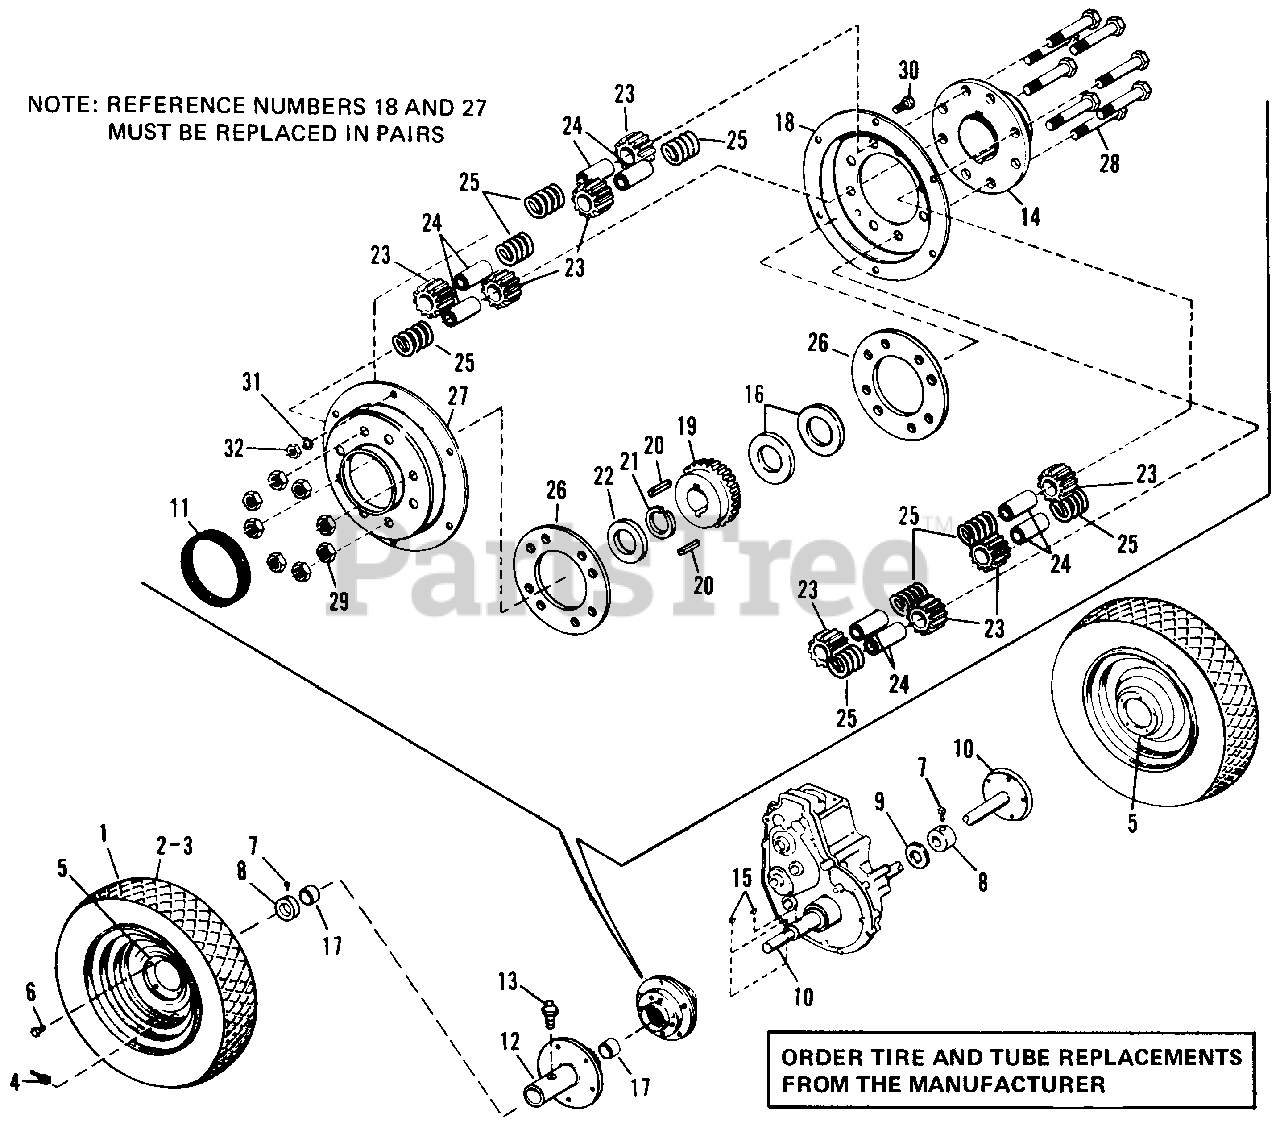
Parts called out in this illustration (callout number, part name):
1	Wheel & Tire Assy.
4	Valve Stem
5	Wheel Drive
7	Set Screw, 5/16"-18 x 3/8"
8	Axle Collar
11	Differential Cover Seal
12	R.H. Wheel Hub Assy.
13	Grease Fitting
14	Differential Carrier
16	Axle Washer
18	Differential Cover
19	Differential Gear
20	Hi-Pro Key
21	Retaining Ring
22	Axle Washer
23	Differential Pinion
24	Differential Pinion Spindle
26	Ring Spacer
27	Differential Cover
28	Hex Capscrew, 3/8"-16 x 2-1/2"
29	Full Hex Lock Nut, 3/8"-16
30	Hex Capscrew, 1/4"-20 x 5/8"
31	Lockwasher, 1/4"
32	Full Hex Nut, 1/4"-20
